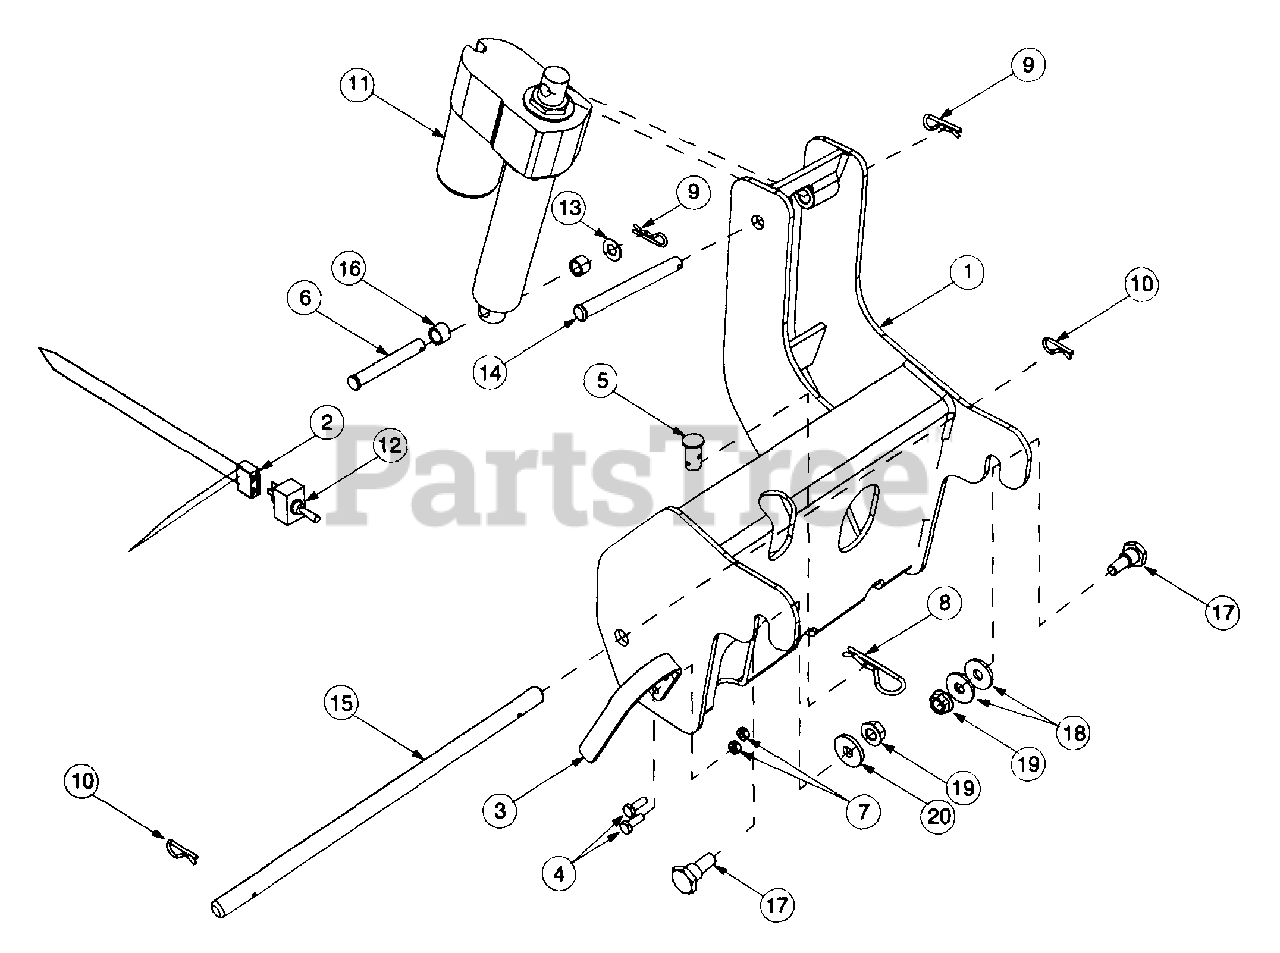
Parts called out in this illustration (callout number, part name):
1	Sleeve Hitch Bracket Assembly
2	Electric Lift Cylinder Wiring Harness
4	Hex Cap Screw, 1/4-20 x .75 GR5
5	Clevis Pin, .62 Dia.
6	Clevis Pin
7	Hex Lock Nut, 1/4-20
8	Internal Cotter Pin, .148 x 3.0
9	Internal Cotter Pin, .125 x 1.75
10	Internal Cotter Pin
11	Electric Lift Cylinder
12	Toggle Switch
13	Flat Washer, .510 x 1.0 x .060
14	Hinge Pin
15	Hitch Rod
16	Spacer, .542 x .750 x .500
17	Shoulder Bolt, .625 x .5, 7/16-20
18	Flat Washer,.450 x 1.25 x .150
19	Flange Lock Nut, 7/16 x 20 GR8
20	Flat Washer, .450 x 1.25 x .170
